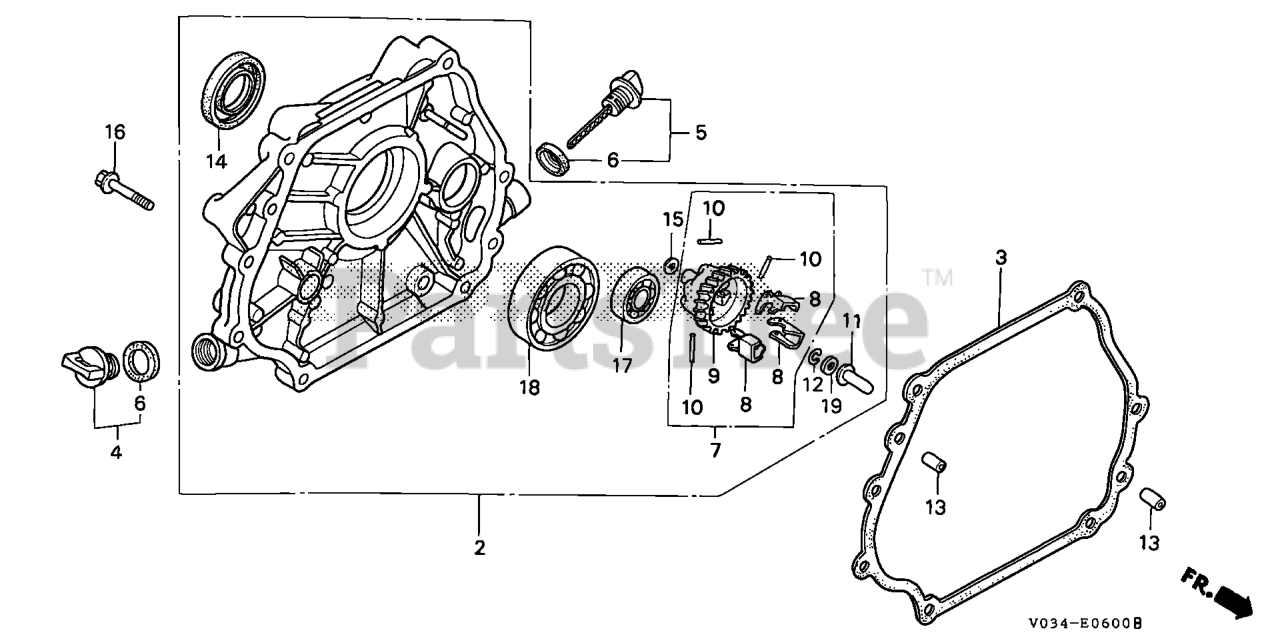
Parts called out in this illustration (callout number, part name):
2	COVER ASSY., CRANKCASE (S-TYPE)
2	COVER ASSY., CRANKCASE
3	GASKET, CASE COVER Use up to Engine SN 2949254.
3	GASKET, CASE COVER
4	CAP ASSY., OIL FILLER
5	CAP ASSY., OIL FILLER
6	GASKET, OIL FILLER CAP
7	GOVERNOR ASSY.
8	WEIGHT, GOVERNOR
9	HOLDER, GOVERNOR WEIGHT
10	PIN, GOVERNOR WEIGHT
11	SLIDER, GOVERNOR
12	CLIP, GOVERNOR HOLDER
13	PIN, DOWEL (8X12)
14	OIL SEAL (35X52X8)
15	WASHER, PLAIN (6MM)
16	BOLT, FLANGE (8X40) Use up to Engine SN 1003236.
17	BEARING, RADIAL BALL (6202)
18	BEARING, RADIAL BALL (6207)
19	WASHER (6X16)
